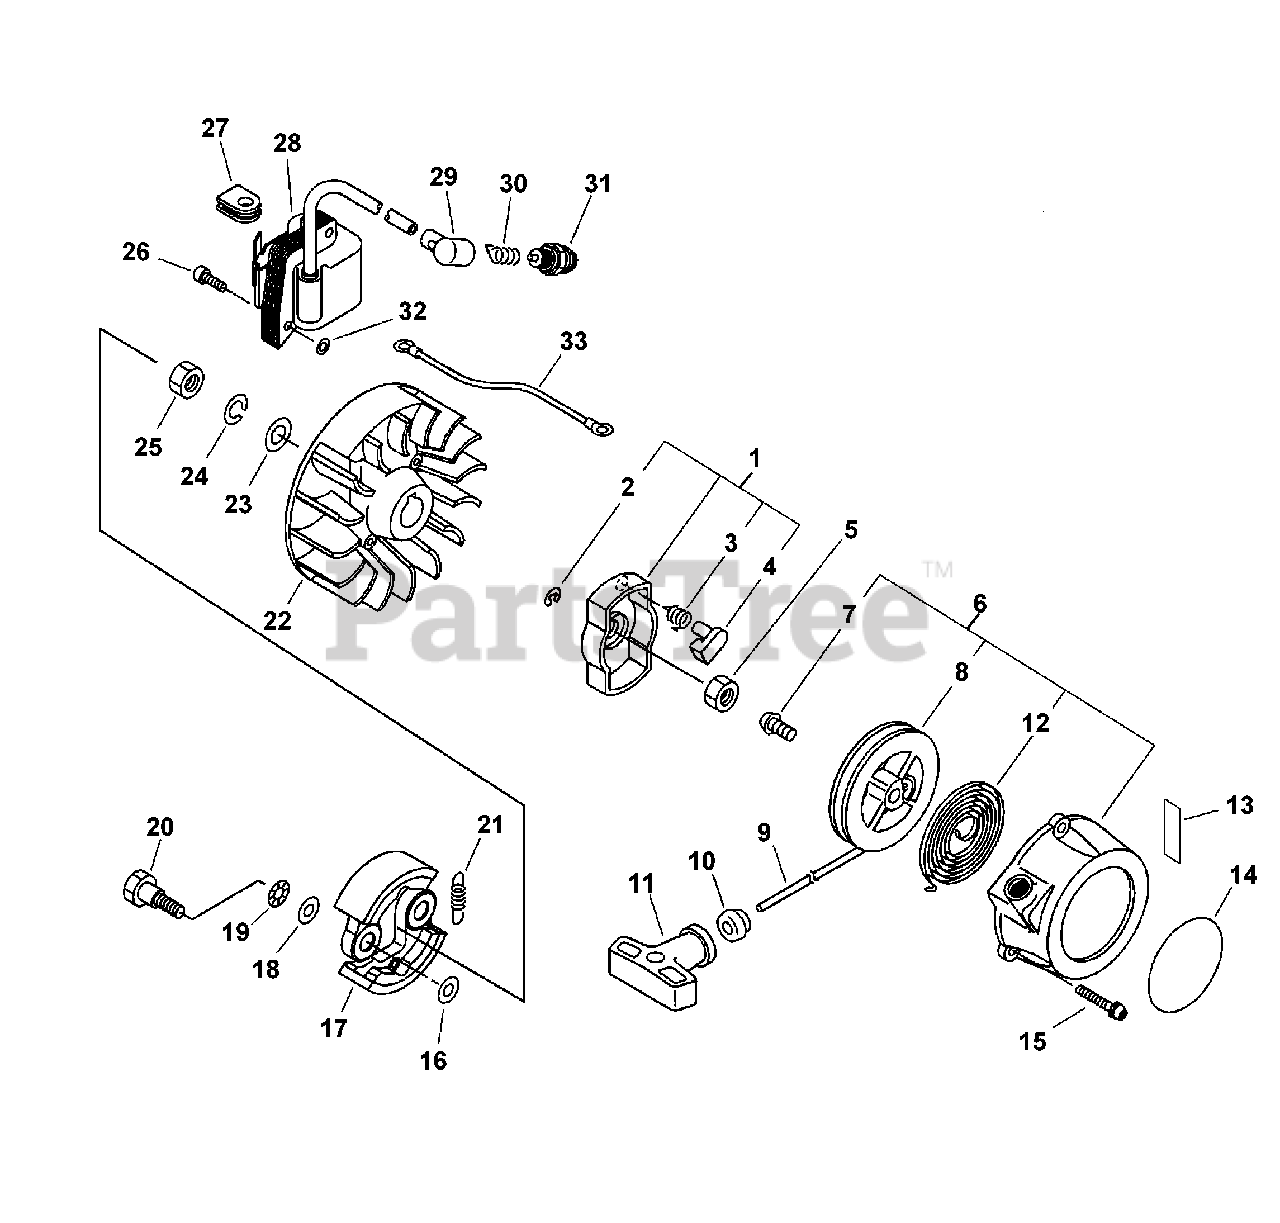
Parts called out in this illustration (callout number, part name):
1	PAWL ASSY, STARTER
2	E-RING 4
3	SPRING, RETURN
4	PAWL, STARTER
5	NUT 8×1.25
6	STARTER ASSY, RECOIL
8	REEL, ROPE
9	ROPE, STARTER 3.5×850
10	GUIDE, ROPE
11	GRIP, STARTER
12	SPRING, RECOIL
13	LABEL, CAUTION - HOT
14	LABEL, ECHO
15	SCREW 4×14
16	WASHER 6
17	SHOE, CLUTCH
18	WASHER 8
19	WASHER 8.5×16×0.5
20	BOLT, CLUTCH 8×7.9×M6
21	SPRING, TENSION
22	FLYWHEEL
23	WASHER 8.5×16×1.2
24	WASHER, SPRING 8
25	NUT 8×1.25
26	BOLT 4×22
28	COIL, IGNITION
29	CAP, SPARK PLUG
30	TERMINAL, SPARK PLUG
31	SPARK PLUG - BPM7Y
